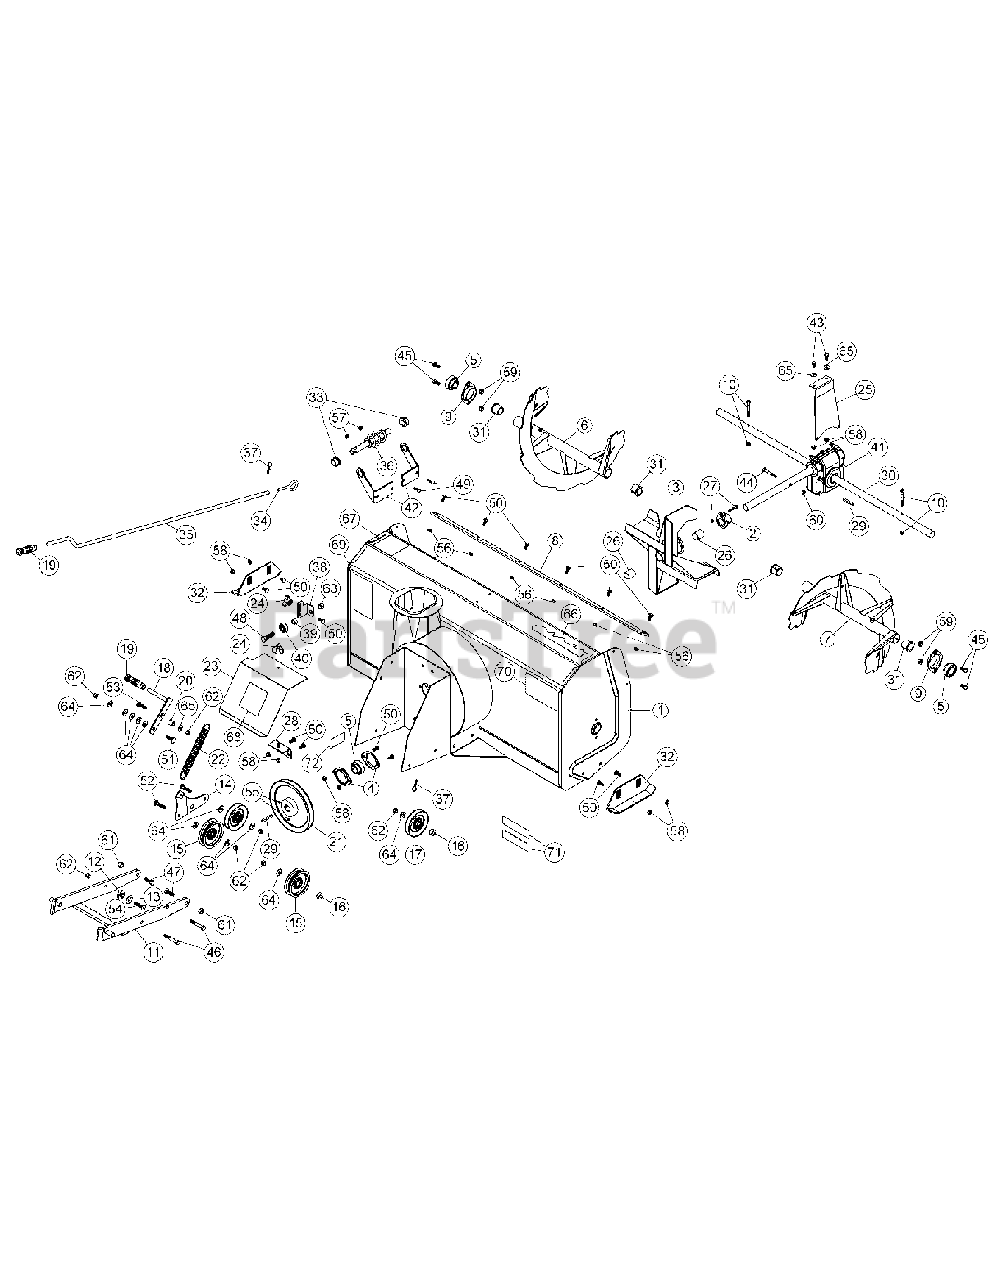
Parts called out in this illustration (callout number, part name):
1	Frame 44"
2	Shear plate
3	Fan
5	Bearing with set screw
6	Auger 44" left
7	Auger 44" right
8	Cutting edge 44"
10	Shear bolt / N.I.L.N. (auger)
11	Male hitch
12	Flange washer
13	Special washer
14	Tension lever
15	Flat pulley
18	Tension arm
25	Gear box support
26	Oil lite bushing
27	Shear bolt / N.I.L.N. (fan)
28	Belt guard support
29	Key 1/4" x 1/4" x 2"
31	Rotation bushing
33	Rotation bushing
34	Handle hook
36	Rotation worm
37	Hair pin 2.5mm
41	Gear box left rotation
42	Worm supports
43	Hex. bolt 5/16" n.c. x 3/4"
44	Hex. bolt 5/16" n.c. x 2 1/4" GR8
45	Hex. bolt 3/8" n.c. x 3/4"
46	Hex. bolt 3/8" n.c. x 2 1/2"
47	Hex. bolt 7/16" n.c. x 1 1/4"
48	Hex. bolt 1/2" n.c. x 1 3/4"
49	Carriage bolt 1/4" n.c. x 1"
50	Carriage bolt 5/16" n.c. x 3/4"
51	Carriage bolt 3/8" n.c. x 1 1/4"
52	Carriage bolt 3/8" n.c. x 1 3/4"
53	Carriage bolt 3/8" n.c. x 1-1/2"
54	Hex socket f.h. cap screw 3/8" n.c. x 1-3/4"
55	Hex. socket set screw 5/16" n.c. x 5/16"
56	Stover lock nut 5/16" n.c.
57	Flange nut 1/4" n.c.
58	Flange nut 5/16" n.c.
59	Flange nut 3/8" n.c.
60	Nylon insert lock nut 5/16" n.c.
61	Nylon insert lock nut 7/16" n.c.
62	Nylon insert lock nut 3/8" n.c.
63	Nylon Insert lock nut 1/2" n.c.
64	Flat washer 7/16" hole
65	Flat washer 3/8" hole
66	Decal Cub Cadet
67	Decal danger auger
68	Decal danger belts
69	Decal read instructions
70	Decal warning safety
72	Serial number
